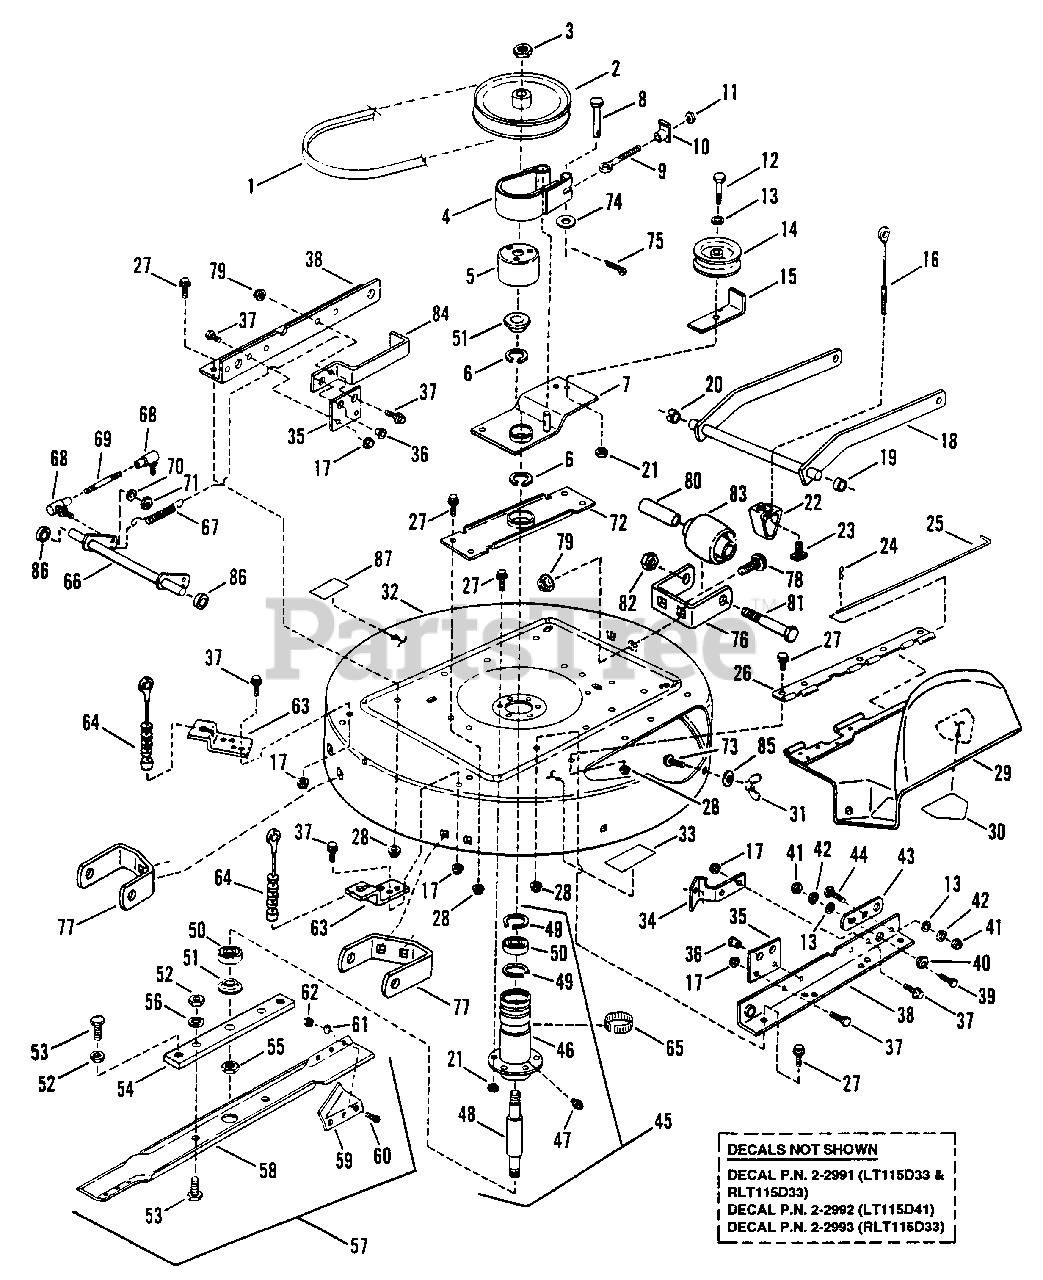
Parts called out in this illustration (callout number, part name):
1	BELT, 33" Drive Kevlar (A-59 61" OD)
2	PULLEY, 8" O.D.
3	NUT, 3/4-16 Hex Jam
4	BAND, Brake Assembly
5	DRUM, Brake
6	RING, 2" External Retaining
7	ARM, Idler
8	PIN, 1/4 x 1 1/4" Clevis
9	BOLT, 1/4-20 Eye
10	NUT, 1/4-20 Tee
11	NUT, 1/4-20 Hex GR 5 YZ
12	SCREW, 3/8-24 x 1 1/2" Hex Head Cap
13	WASHER, 3/8 SAE
14	PULLEY, Idler, 4.12 O.D.
15	GUIDE, Belt
16	CABLE, Front Lift 6.12"
17	NUT, 5/16-18 Hex Flange Lock
18	LIFT, Front Arm
19	RING, Red
20	RING, Black (Left Side)(5/8" ID x .44" Wide)
21	NUT, 3/8-24 Hex Lock
22	BRACKET, Front Lift Hanger
23	T-NUT, 5/16-18
24	PIN, Hair 3/32" x 1.5"
25	PIN, Hinge
26	HINGE, Deflector
27	BOLT, 3/8-16 x 3/4" Hex Flange Lock
28	NUT, 3/8-16 Hex Flange Lock
29	ASSEMBLY, Deflector
30	DECAL, Danger
31	WING-NUT, 5/16-18
32	DECK, Cutting, 33"
33	DECAL, Caution
34	ANCHOR, Brake
35	BRACKET, Cross-Shaft
36	BEARING, Cross-Shaft Bracket
37	BOLT, 5/16-18 x 1/2" Hex Flange Lock
38	RAl L, Side
39	SCREW, 3/8-16 x 1" Hex Head Tap
40	ECCENTRIC, Leveling
41	NUT, 3/8-16 Hex
42	WASHER, 3/8 Split Lock
43	LINK, Adjustment
44	BOLT, 3/8-16 x 3/4" Carriage
45	ASSEMBLY, Spindle
46	HOUSING, Spindle 5.575" Tall
47	FITTING, Lube (Press into .187" hole, no ball)
48	SPINDLE, 33" Mower Deck 8.26" Long
49	RING, Retaining EXT 1.75"
50	BEARING, Spindle
51	WASHER, Spindle
52	NUT, 1/4-20 Hex Jam
53	SCREW, 1/2-20 Hex Head Cap
54	HOLDER, Blade
55	NUT, 5/8-18 Hex Lock
56	WASHER, 1/2 Int. Tooth Lock
58	BLADE, 33" Mower Deck
59	AIR-LIFT
60	SCREW, 5/16-24 x 11/16" Machine
61	WASHER, 5/16 Internal Tooth Lock
62	NUT, 5/16-24 Hex
63	BRACKET, Rear Lift
64	CABLE, Support 4.25" 8 Spacers
65	RING, Tolerance 2.0"
66	CROSS-SHAFT
67	SPRING
68	BALL-JOINT
69	LINK, Ball Joint
70	WASHER, 1/4 Int. Tooth Lock
71	NUT, 1/4-28 Hex
72	BRACE, Spindle
73	BOLT, 5/16-18 x 3/4" Short Neck Carriage
74	WASHER .28 x .63 x .065 YZ
75	COTTER-PIN, 3/32 x 3/4"
76	BRACKET, Gage Wheel (Front)
77	BRACKET, Gage Wheel (Rear)
78	BOLT, 5/16-18 x 1/2" Short Neck Carriage
79	NUT, 5/16-18 Hex Flange Lock
80	SPACER .625 OD x .423 ID x 3" L
81	SCREW, 3/8-24 x 3 3/4" Hex Head Cap
82	NUT, 3/8-24 Hex Lock
83	WHEEL, Gage
84	GUIDE, Belt
85	WASHER, 5/16 Flat
86	SPACER
87	DECAL, Caution
